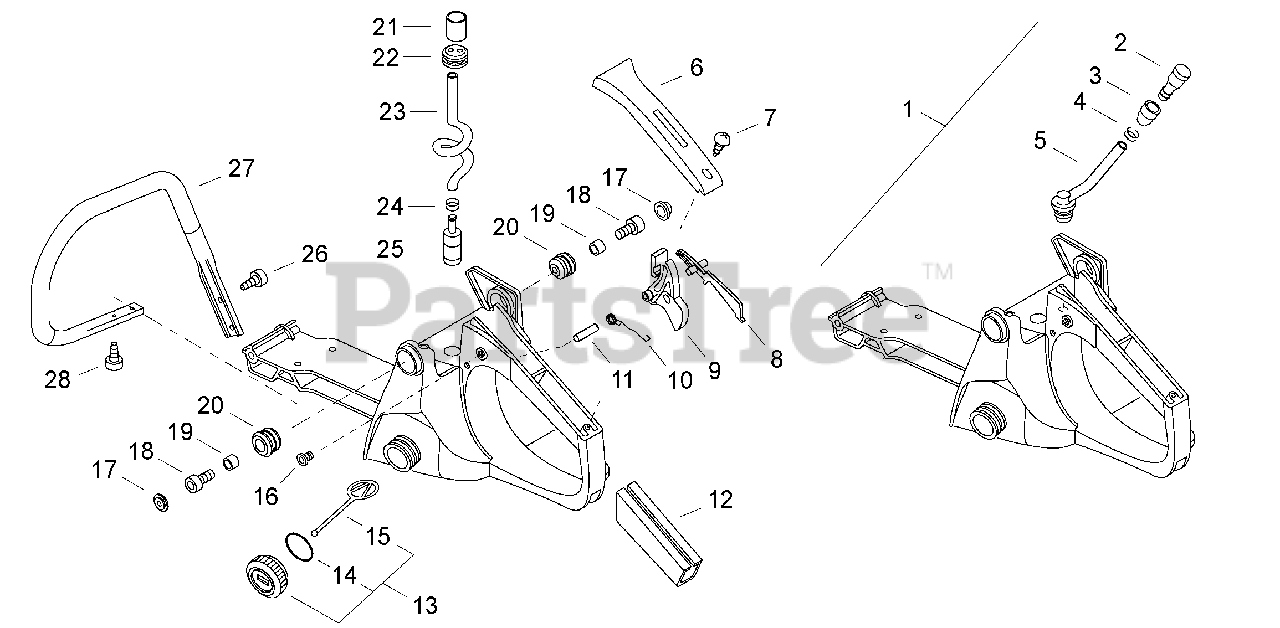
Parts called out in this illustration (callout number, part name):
1	HANDLE ASSY - REAR
2	VENT, FUEL TANK
3	COVER, VENT
4	CLIP - 6.5
5	PIPE - VENT
6	COVER, HANDLE
7	SCREW - 4X14
8	LEVER, TRIGGER LOCKOUT
9	TRIGGER, THROTTLE
10	SPRING, TRIGGER
11	PIN - SPRING -- 4X30
12	GRIP, HANDLE
13	CAP ASSY - BLACK
14	O-RING - 22
15	CONNECTOR, CAP
17	CAP, CUSHION
18	SCREW - 4X20
20	CUSHION
22	GROMMET
23	PIPE, FUEL - SPIRAL
24	CLIP - 6
25	FILTER, FUEL
26	SCREW - 5X20 -- TAPPING
27	HANDLE - FRONT
28	SCREW - 5X16
